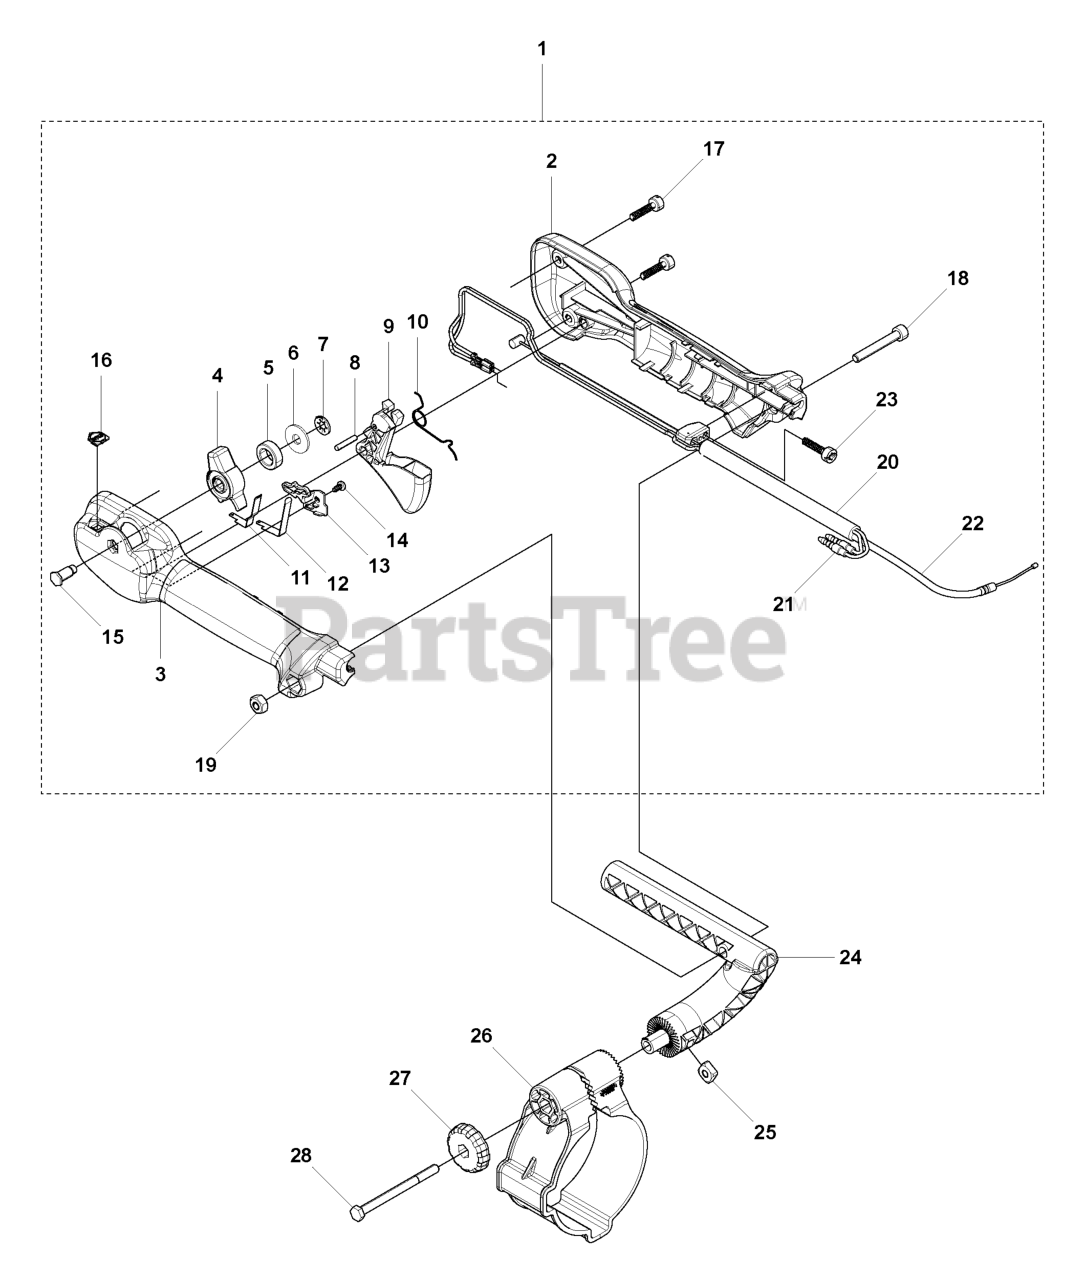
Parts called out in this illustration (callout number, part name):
1	LEVER
5	SPRING RUBBER
9	THROTTLE TRIGGER
11	CONTACT SPRING
12	CONTACT SPRING
18	SCREW
24	BRACKET
26	HOLDER TH
